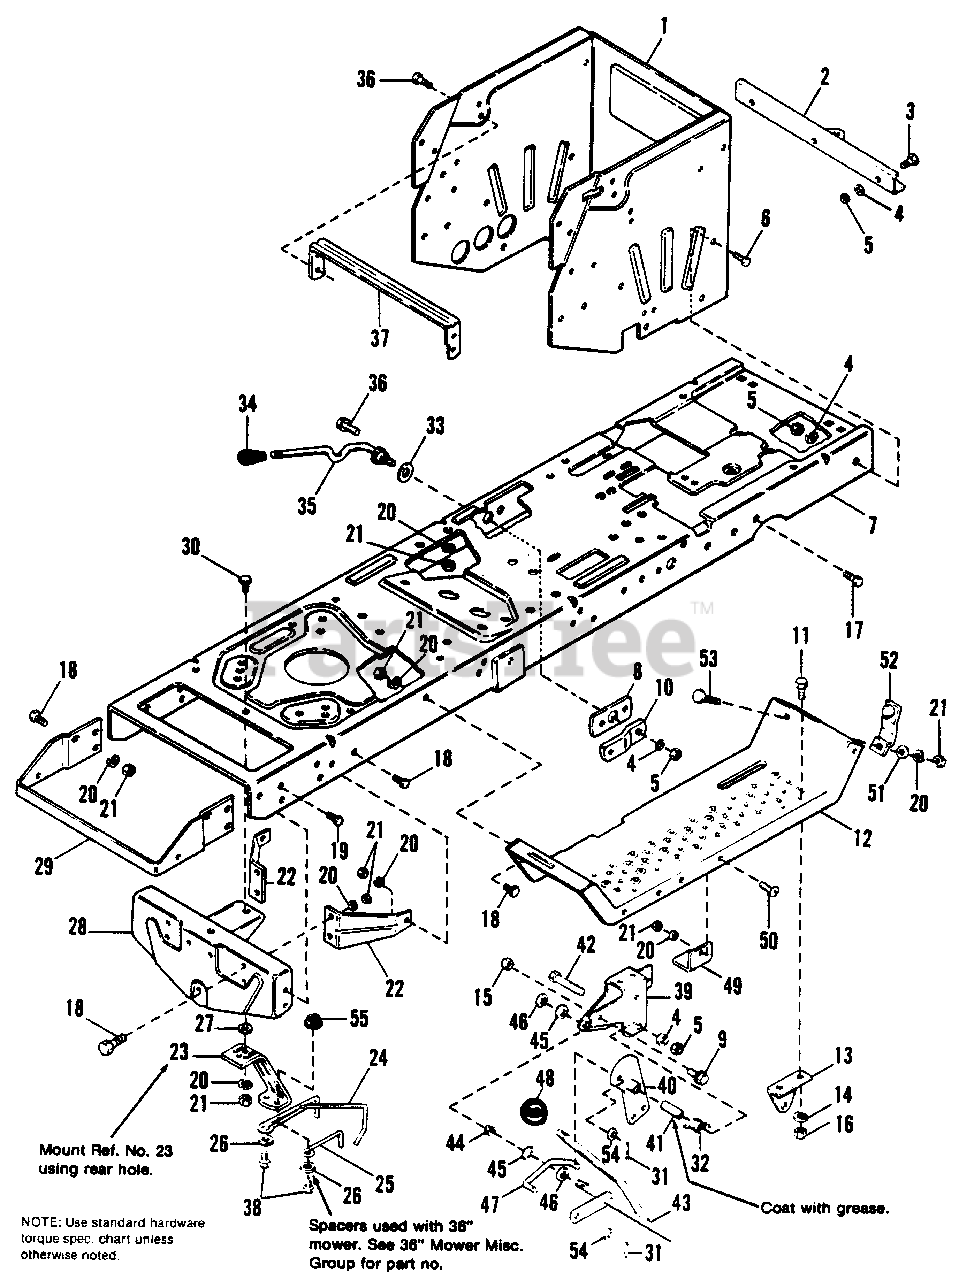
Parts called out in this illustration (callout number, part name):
1	SUPPORT, Axle, Wrapper
2	BAR, Draw
3	CAPSCREW, Hex Hd., 3/8-16 x 1
4	LOCKWASHER, 3/8
5	NUT, Hex, Full, 3/8-16
6	CAPSCREW, Hex Hd., 3/8-16 x 1-1/2
8	BAR, Support
9	CAPSCREW, Hex Wash. Hd., 1/4-20 x 5/8
10	ARM, Support
11	CAPSCREW, Hex Hd., 1/4-20 x 5/8
13	SUPPORT, Clutch
14	LOCKWASHER, 1/4
15	NUT, Flange, Whizlock, 1/4-20
16	NUT, Hex, 1/4-20
17	CAPSCREW, 3/8-16 x 3/4
18	CAPSCREW, Hex Hd., 5/16-18 x 3/4
19	SCREW, Hex Taptite, 5/16-18 x 3/4
20	LOCKWASHER, 5/16
21	NUT, Hex, Full, 5/16-18
22	BRACE, Axle Support
26	WASHER, Plain, 1/4
27	WASHER, Plain, 5/16
28	SUPPORT, Axle
29	SUPPORT, Hood
30	CAPSCREW, Hex Hd., 5/16-18 x 1
31	PIN, Cotter, 3/32 x 3/4
34	GRIP
35	HANDLE, Lift
36	SCREW, Hex, Washer Hd., Taptite, 5/16-18 x 1/2
37	BRACE, Seat
38	CAPSCREW, 5/16-18 x 1-1/2
39	BRACKET, P.T.O.
40	ARM ASSY., P.T.O. Rod
42	CAPSCREW. Hex Hd., 3/8-16 x 2/1-4
43	HANDLE ASSY., P.T.O.
45	WASHER on P.T.O. Link
46	RING, Snap
47	LINK, P.T.O.
49	UP-STOP, Mower
50	SCREW, Truss Hd., Slotted, 5/16-18 x 3/4
52	LATCH ASSY.
53	BOLT, Carriage, 5/16-18 x 3/4
55	NUT, Lock, Flange 5/16-18
56	CAPSCREW, Hex Wash. Hd., 1/4-2 x 1-1/2
